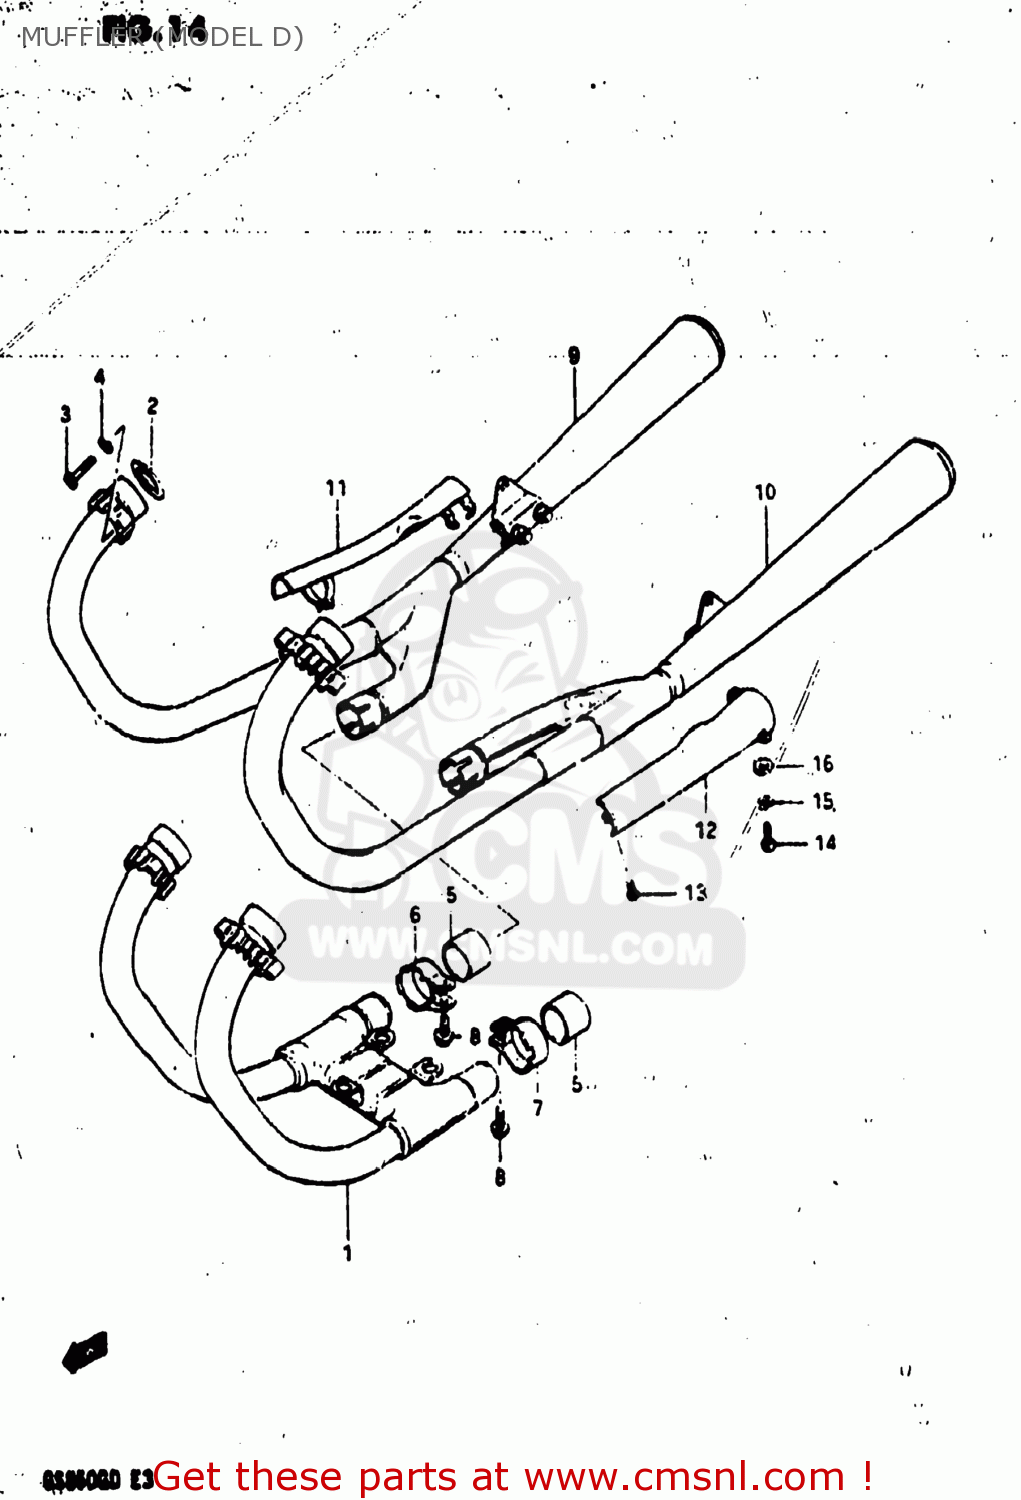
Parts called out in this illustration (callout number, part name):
1	PIPE,EXHAUST
2	GASKET,EXHAUST PIPE (NAS)
3	BOLT 8X40
4	LOCK WASHER
5	CONNECTOR,MUFFLER
6	CLAMP,MUFFLER CONNECTOR,R
7	CLAMP,MUFFLER CONNECTOR,L
8	BOLT
9	MUFFLER ASSEMBLY
10	MUFFLER ASSEMBLY
11	COVER,MUFFLER
12	COVER,MUFFLER,LEFT
13	SCREW
14	SCREW
15	LOCK WASHER
16	WASHER
